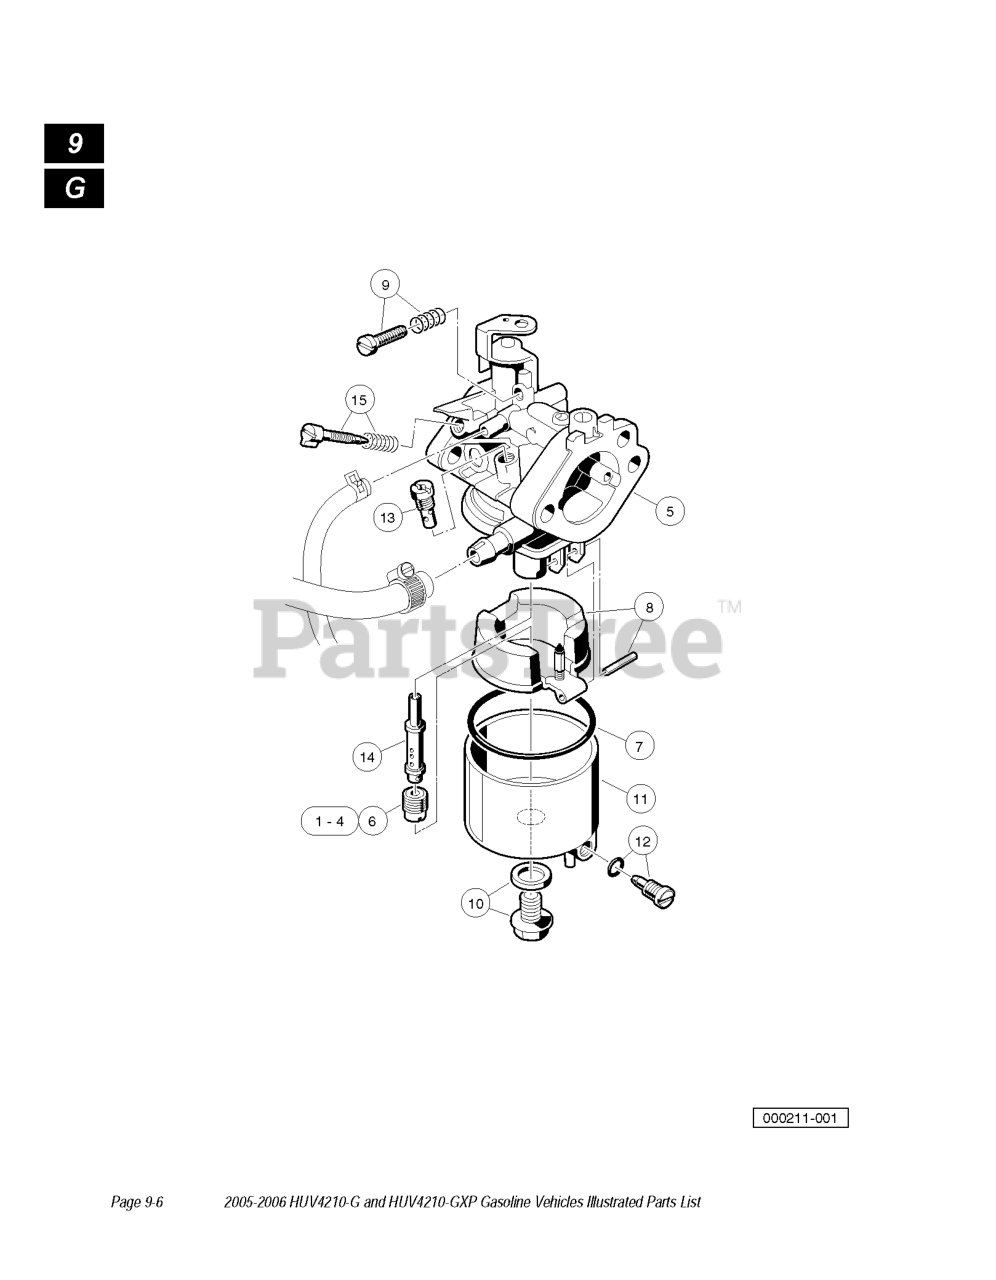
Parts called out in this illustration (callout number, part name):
1	JET, HIGH ALTITUDE OHV
2	JET, HIGH ALTITUDE OHV
3	JET, HIGH ALTITUDE OHV
4	JET, HIGH ALTITUDE JET
5	CARBURETOR ASSY, FE290D
6	JET, HIGH ALTITUDE OHV
7	GASKET, CARB. BOWL OHV
8	FLOAT ASSEMBLY
9	SCREW ASSEMBLY
11	CHAMBER ASSEMBLY - FLOAT
12	SCREW ASSEMBLY
13	JET, #40 PILOT
14	NOZZLE, MAIN
